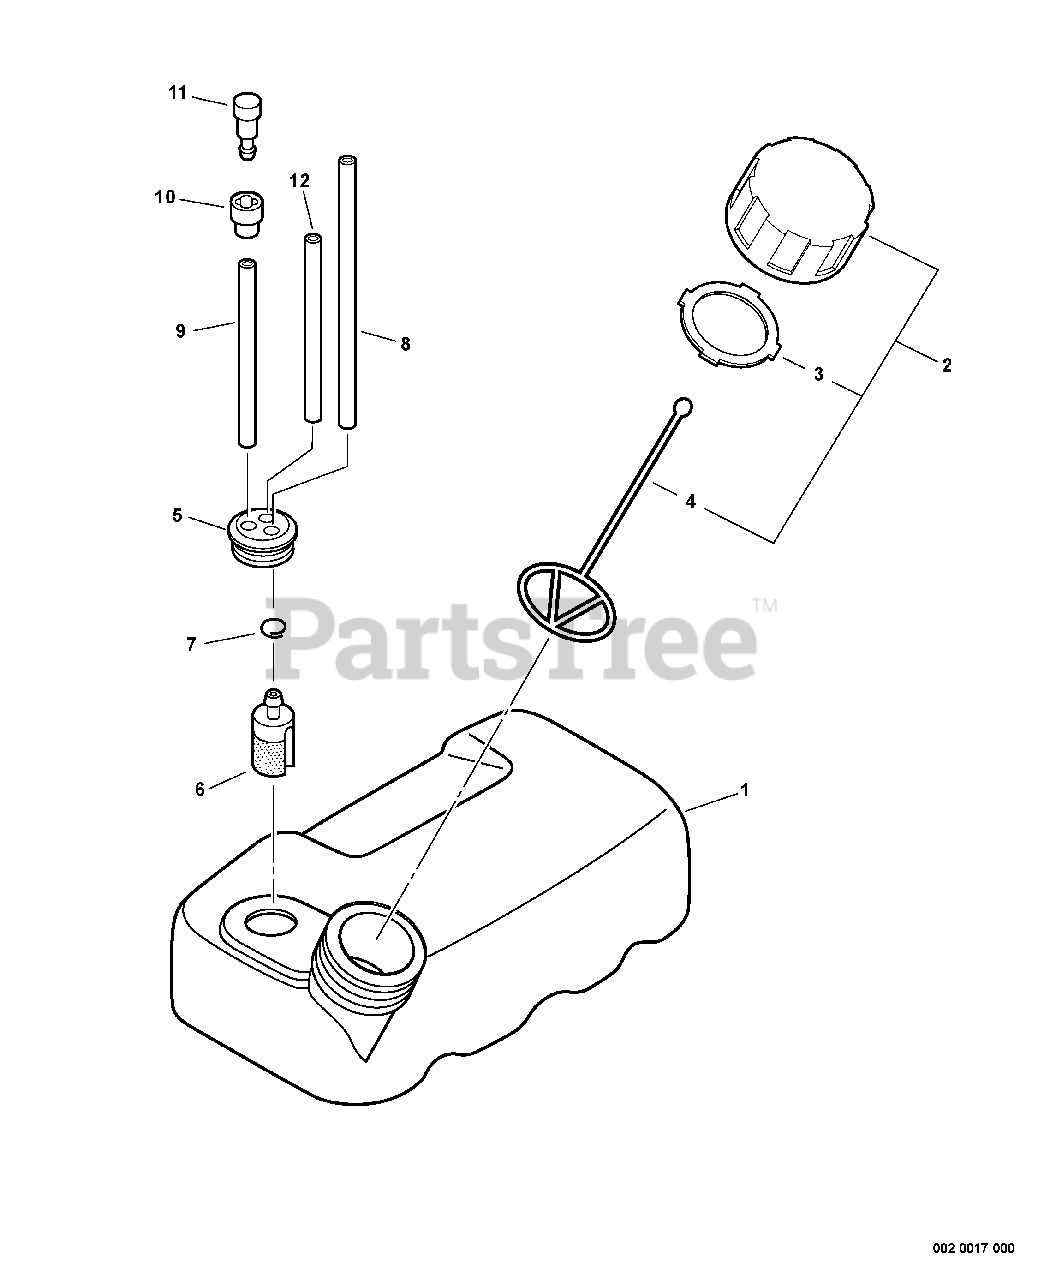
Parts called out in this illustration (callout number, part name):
1	TANK, FUEL
2	CAP ASSY - ORANGE
3	GASKET, CAP
4	CONNECTOR, CAP
5	GROMMET
6	FILTER, FUEL
7	CLIP - 6.5
8	PIPE - 3X6X200 -- BLACK
9	PIPE - 3X6X100 -- BLACK
10	COVER, VENT
11	VENT, FUEL TANK
12	PIPE - 3X6X100 -- CLEAR
13	RePower TUNE-UP KIT
14	RePower TUNE-UP KIT
